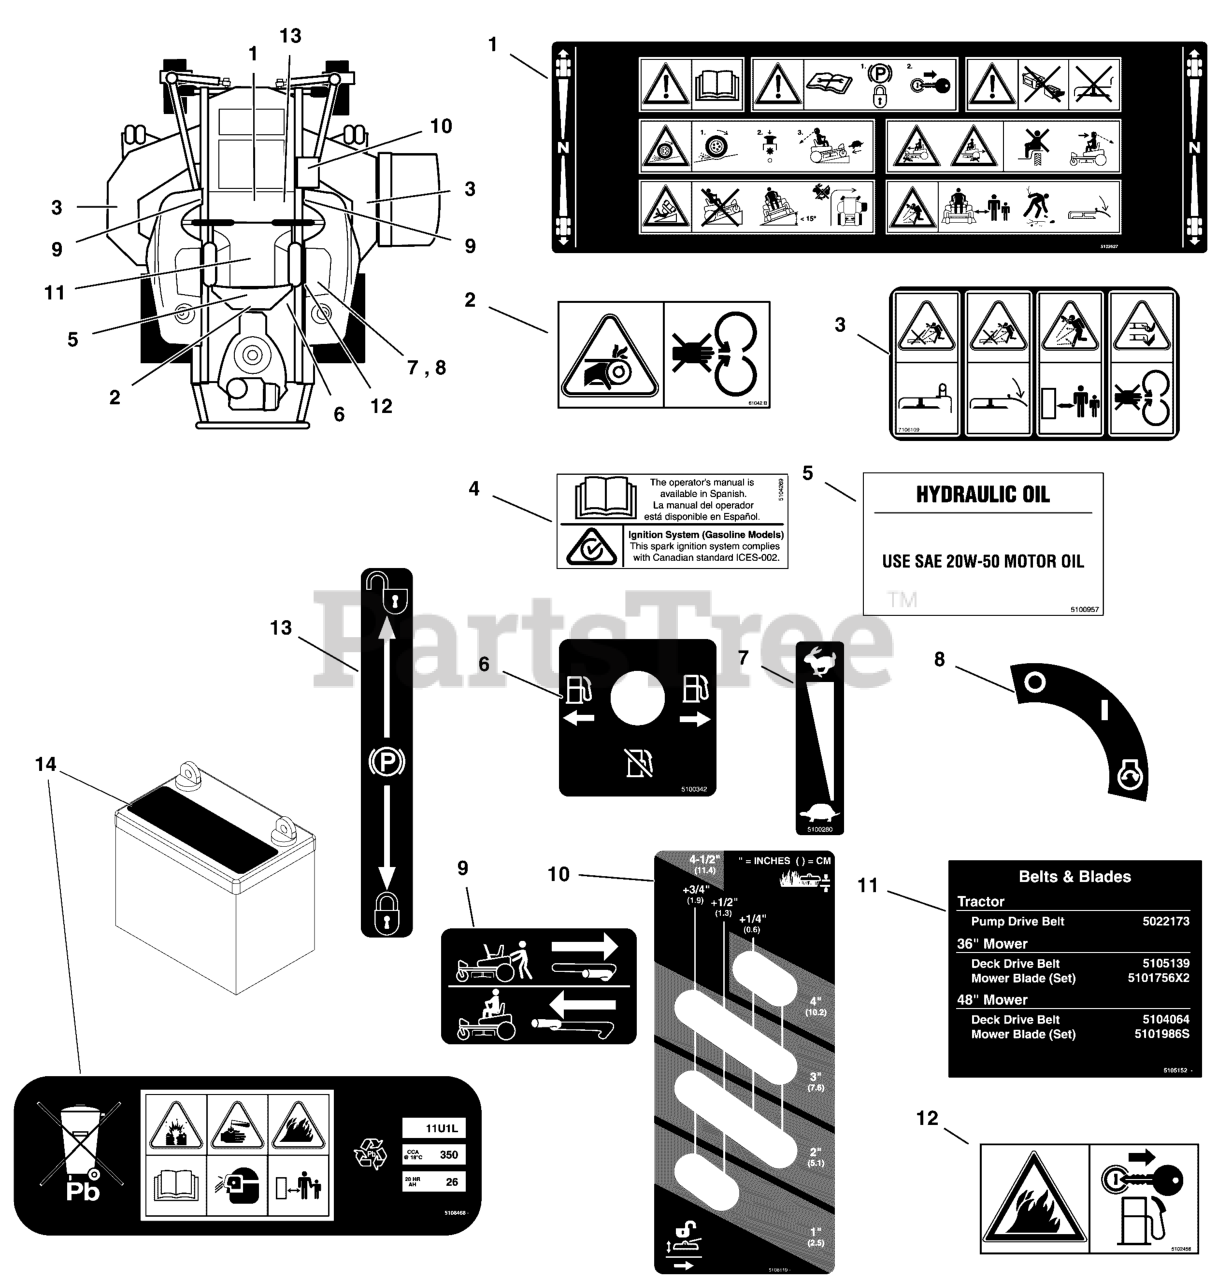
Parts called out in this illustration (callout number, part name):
1	DECAL, MAIN SAFETY, EXPORT
2	DECAL, CE DANGER, HAND IN BELT
3	DECAL, DISCHARGE SAFETY, EXPORT
4	DECAL, SPANISH MANUAL, IGES, C-TICK
5	DECAL, HYDRAULIC OIL, 20W50
6	DECAL, FUEL VALVE
7	DECAL, THROTTLE CONTROL
8	DECAL, IGNITION SWITCH
9	DECAL, TRANSAXLE RELEASE, WB
10	DECAL, CUTTING HEIGHT, F60 & S50XT
11	DECAL, BELT & BLADE, F60Z
12	DECAL, FIRE ANSI EXPORT
13	DECAL, PARKING BRAKE SYMBOLS
14	DECAL, BATTERY, EXP, 11U1L
